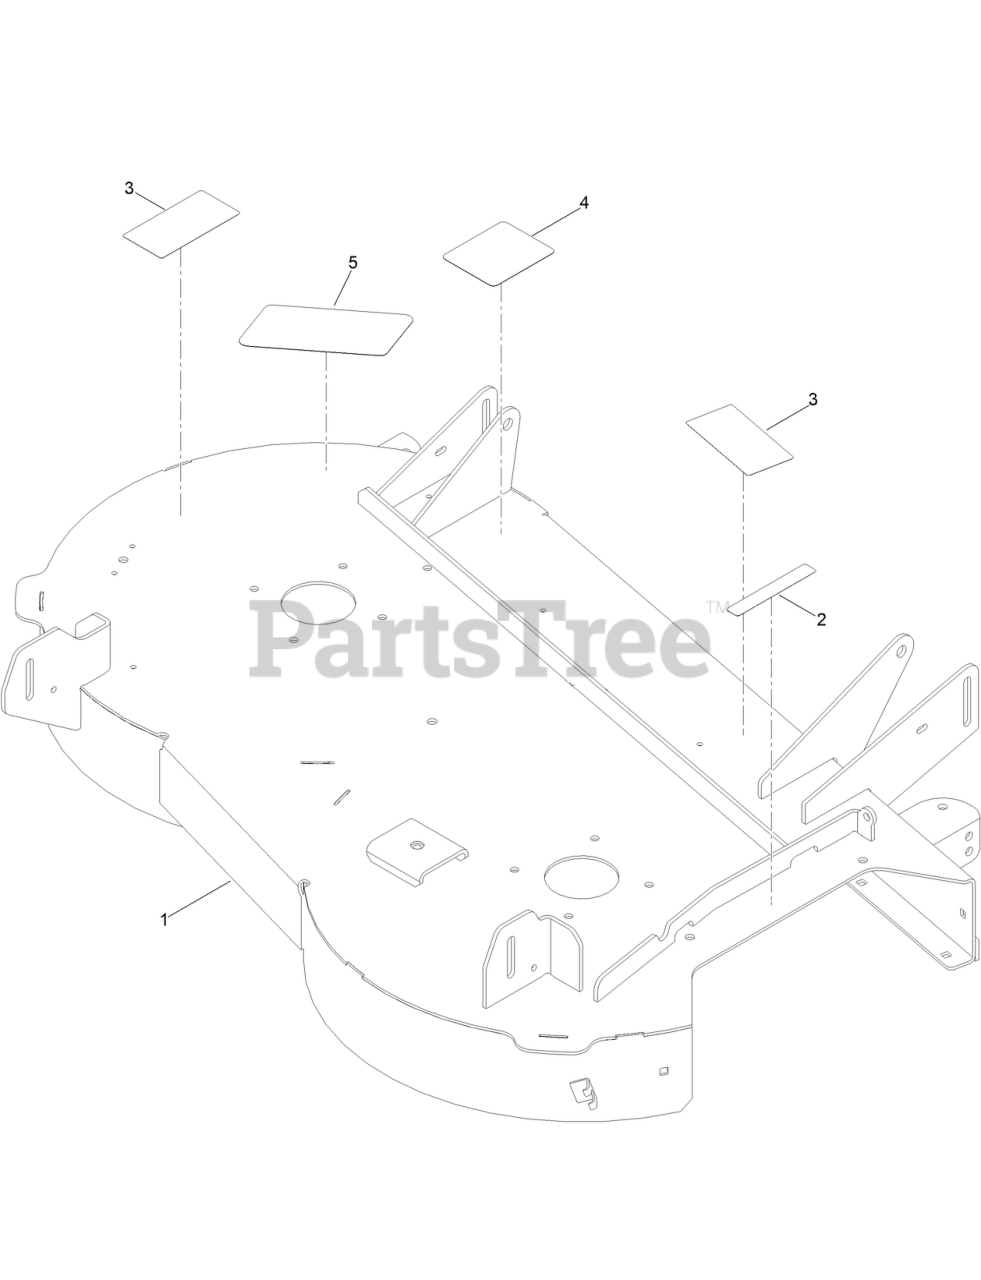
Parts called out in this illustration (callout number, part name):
2	DECAL-DANGER
3	DECAL-DANGER, DECK
4	DECAL-BELT ROUTING 42IN
5	DECAL-DECK 42IN
